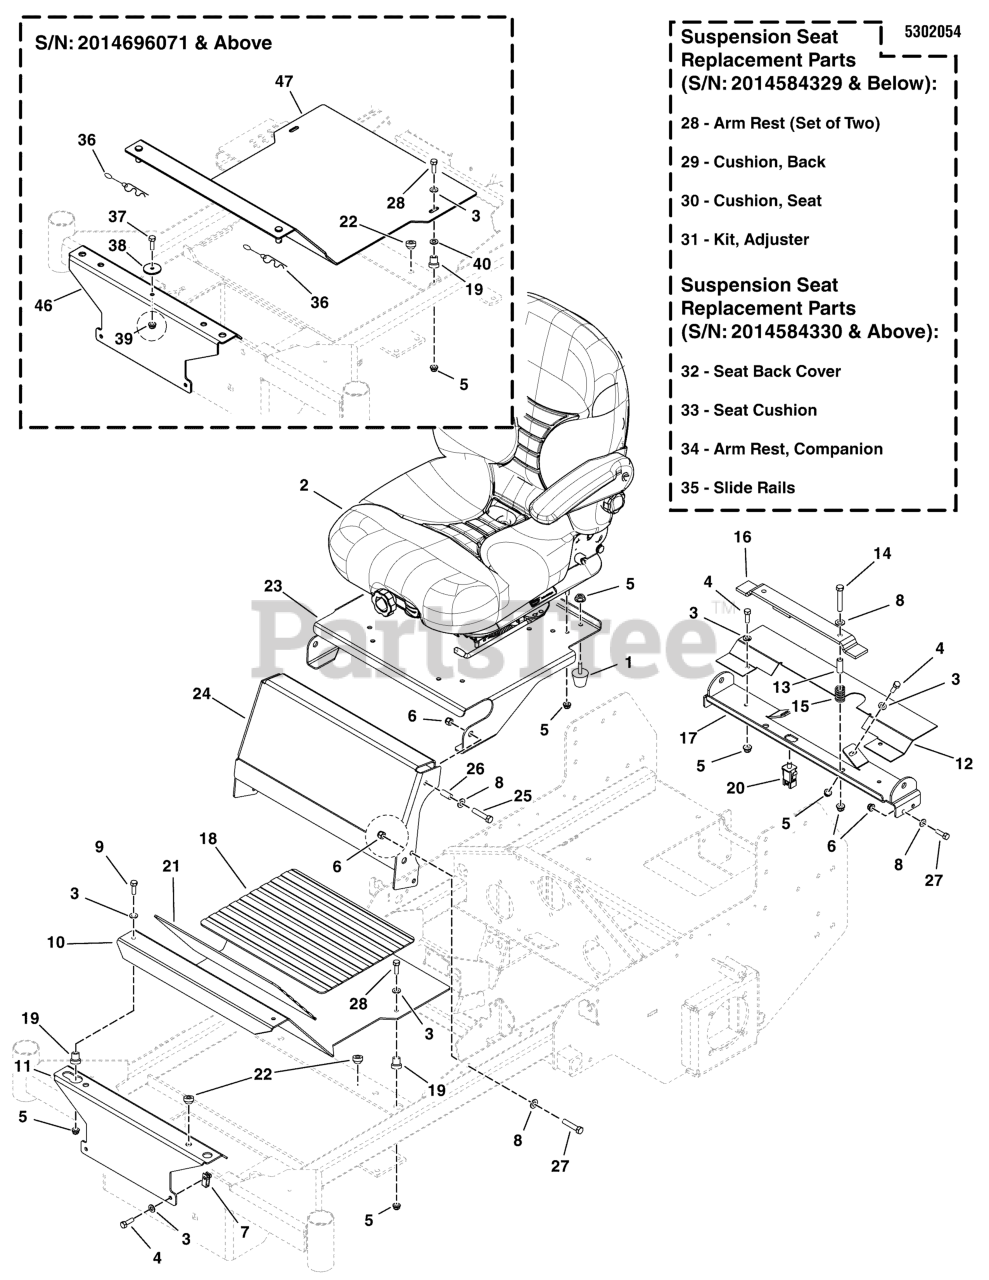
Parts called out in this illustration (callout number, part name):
1	BUMPER, RUBBER 5/16-18
3	WASHER, 5/16" SAE
4	BOLT, 5/16-18 X 1 GD5 YZ
5	NUT, 5/16-18 HEX NYLOCK FLANGE
6	NUT, 3/8-16 HEX NYLOCK FLANGE
7	BODY CLIP, 5/16-18 -1/4 MATERIAL
8	WASHER, 3/8 SAE
9	BOLT, 5/16-18 X 1-1/2 GD5 YZ
10	PLATE, FLOOR - RED
11	WELD, FRONT FLOOR - RED
12	GUARD, HYDRO BELT - RED
13	SPACER, .38 X .50 X 1.25, CZ
14	BOLT, 3/8-16 X 2-1/4" GD5 CZ
15	SPRING-COMP, .625 ID X 1.31 LG X .105 WR
16	WELD, SEAT SWITCH -RED
17	WELD, SEAT SUPPORT - RED
18	SAFETY WALK, 11.50 X 15.00
19	BUSHING, .38 X .88 X .73
20	SWITCH, PLUNGER, NO/NO SNAP-IN
21	SAFETY WALK, FLOOR REST, 8.00 X 15.00
22	MNT, VBRTN, RBBR
25	BOLT, 3/8-16 X 1-1/4" GD5 CZ
26	SPACER, .38 X .50 X .27
27	BOLT, 3/8-16 X 1" GD5 CZ
28	KIT, ARM REST (SV)
29	CUSHION, BACK (SV)
30	CUSHION, SEAT (SV)
31	KIT, ADJUSTER (SV)
32	SEAT BACK COVER
33	SEAT CUSHION
34	ARM REST, COMPANION
35	SLIDE RAILS
36	HAIRPIN COTTER LANYARD ASM, 8"
37	BOLT, 1/4-20 X 3/4 GD5 YZ
38	WASHER, .265 X 1.50 X .109, YZ
39	NUT, 1/4-20 HEX NYLOCK FLANGE
40	WASHER, .350 ID X .65 OD X .160 THK. YZ
